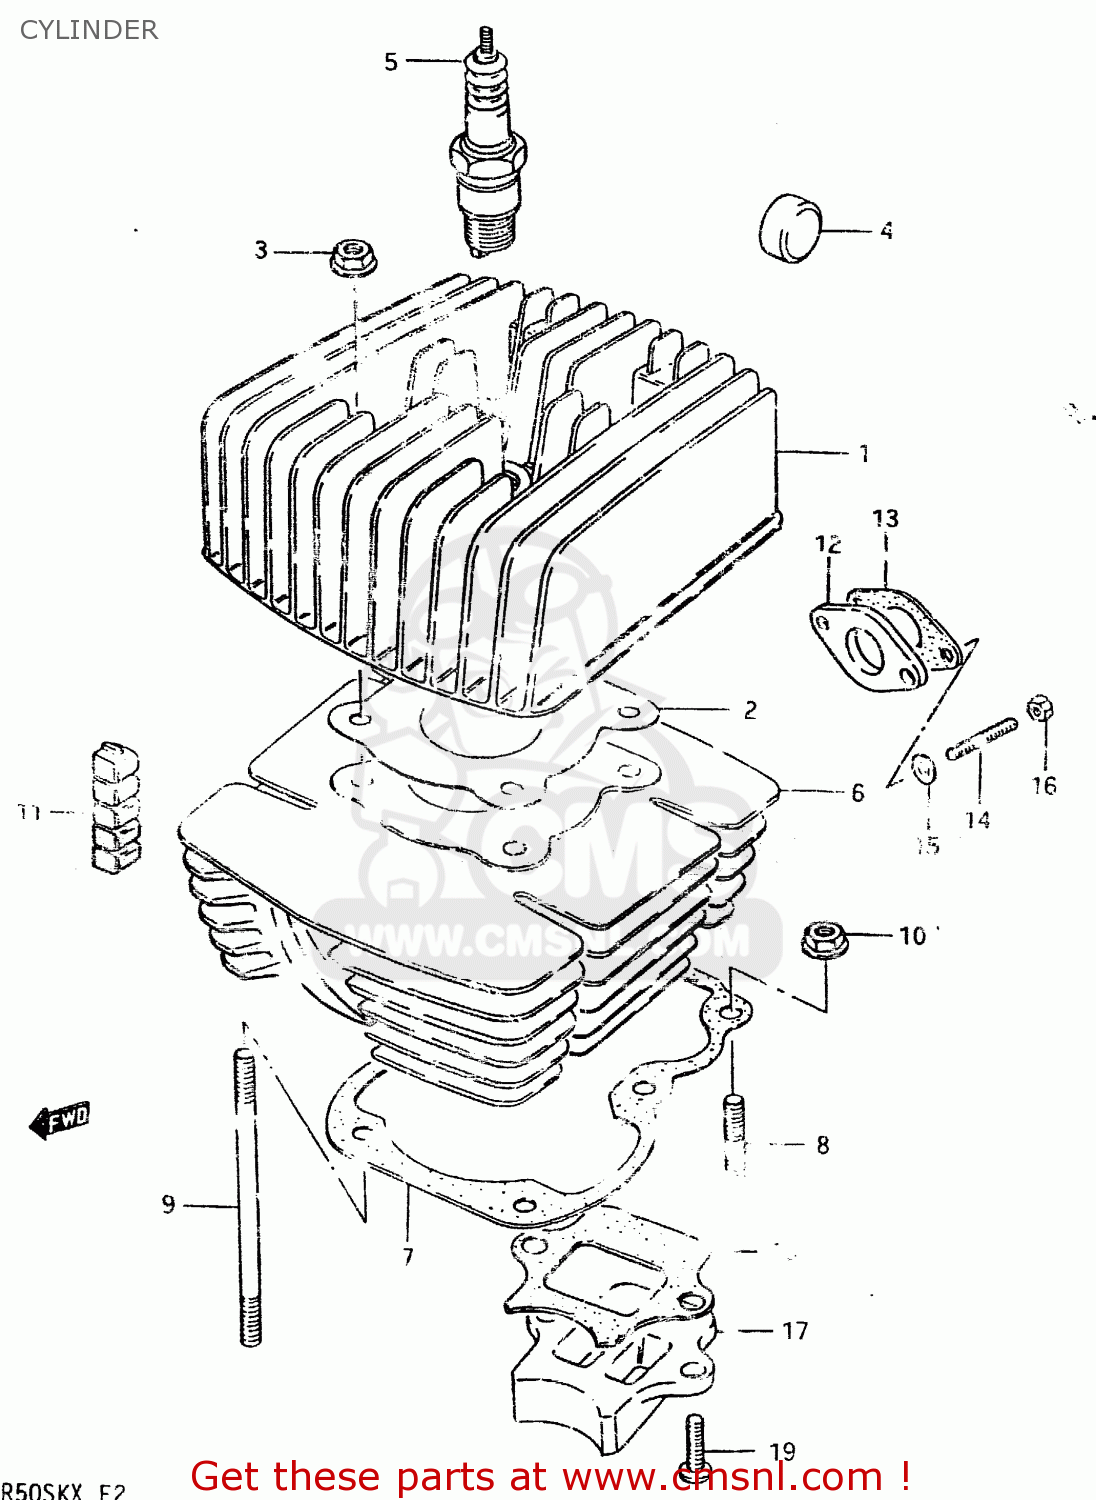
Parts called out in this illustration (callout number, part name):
1	CYLINDER HEAD
2	GASKET,CYLINDER HEAD (NAS)
3	NUT
4	PAD,CYLINDER
5	SPARK PLUG BP8ES
6	CYLINDER
7	GASKET,CYLINDER (MCA)
8	BOLT,STUD
9	STUD 6X16
10	NUT
11	PAD,CYLINDER
12	INSULATOR,CARBURETOR
13	GASKET,CARBURETOR (MCA)
14	STUD BOLT
15	WASHER
16	NUT
17	VALVE ASSY,REED
18	GASKET,REED VALVE (MCA)
19	SCREW
